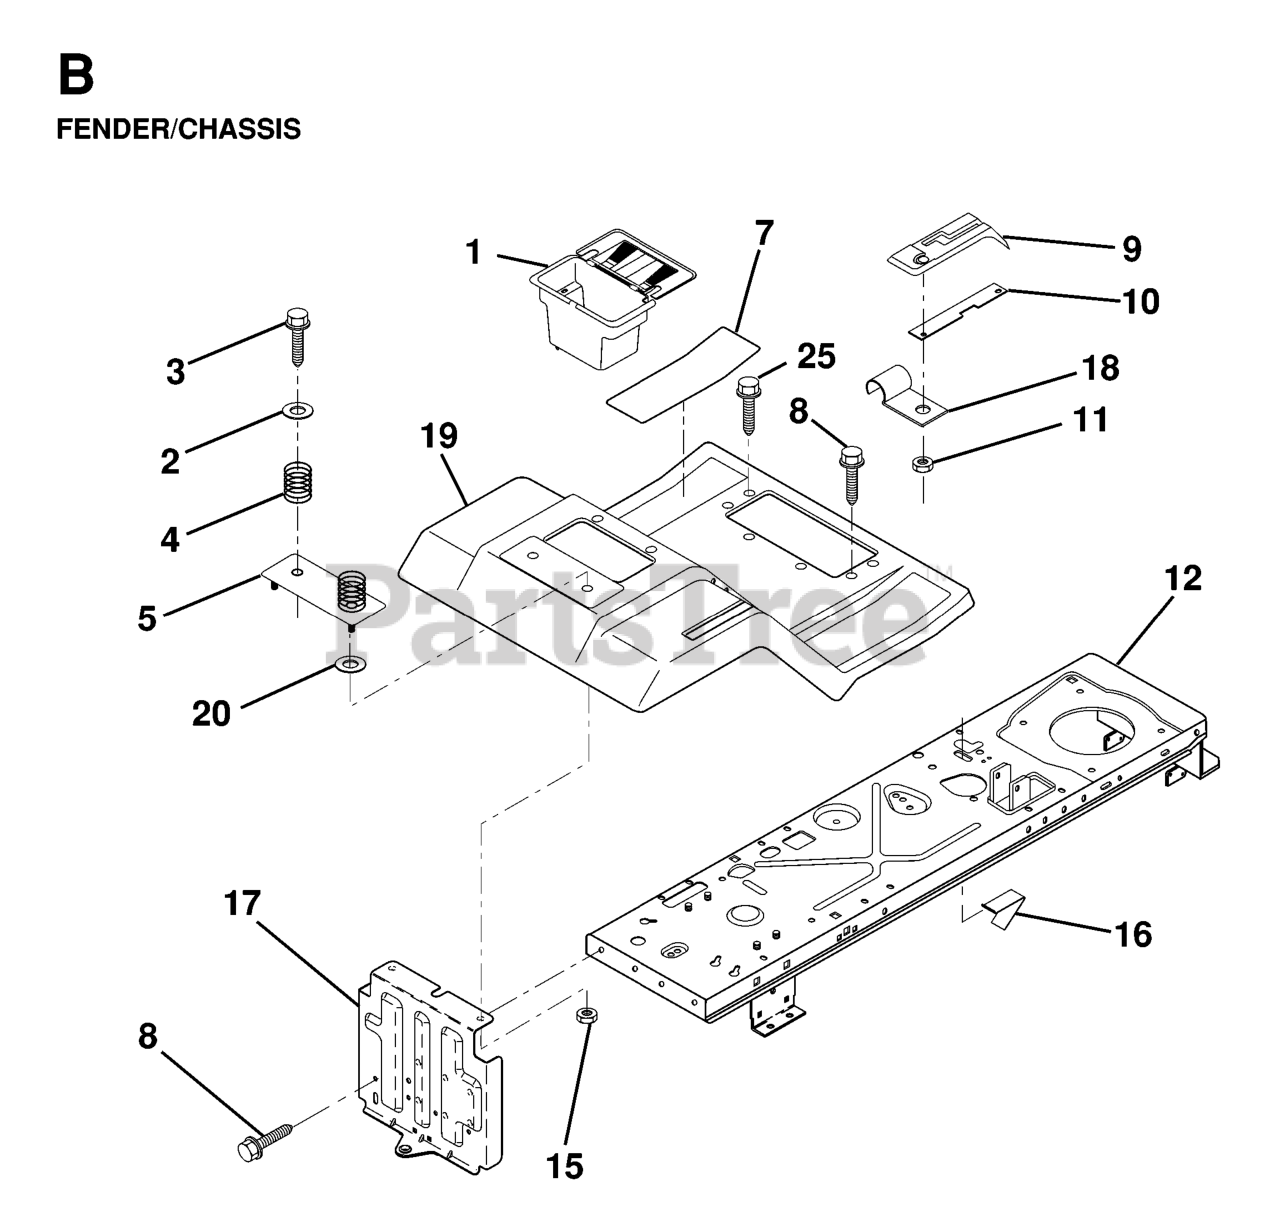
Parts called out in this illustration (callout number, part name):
1	CASE BATTERY MECH HINGE
2	WASHER
3	SCREW
4	SPRING COMPRESSION
5	PLATE ASM BATTERY
7	FOOTREST PAD
8	SCREW.THDROL.5/16-18X3/4.TTY
9	CONSOLE,SHT CONTR
10	BAR, SHIFT LOCK
11	NUT.PUSH.3/16
15	Nut, Keps Blk Hex 1/4-20 UNC
16	SWITCH ACTUATOR
18	CLIP,INSULATOR
19	FENDER/FOOTREST
20	WASHER
25	Screw Hex Wsh Thdroll 5/16-18 x 1
